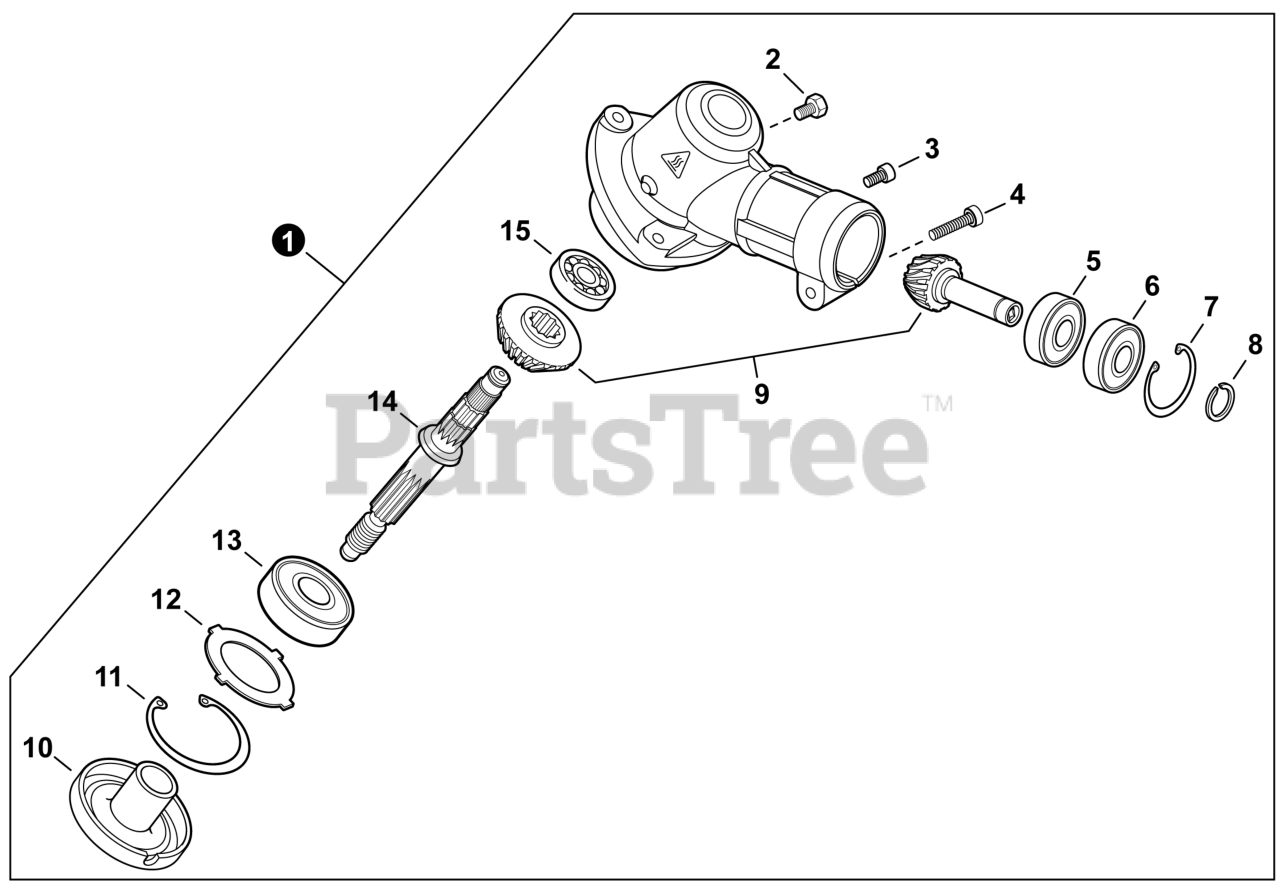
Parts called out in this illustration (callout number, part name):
1	GEAR CASE ASSY
2	BOLT M8x8
3	BOLT, TORX 5x12
4	BOLT, TORX 5x25
5	BEARING, BALL 609A
6	BEARING, BALL 609ZA
7	RING, SNAP 25
8	RING, SNAP 9
9	GEAR SET, BEVEL
10	PLATE, ADAPTOR - UPPER
11	RING, SNAP 32
13	BEARING, BALL 6201
14	SHAFT, GEAR
15	BEARING, BALL 629A
